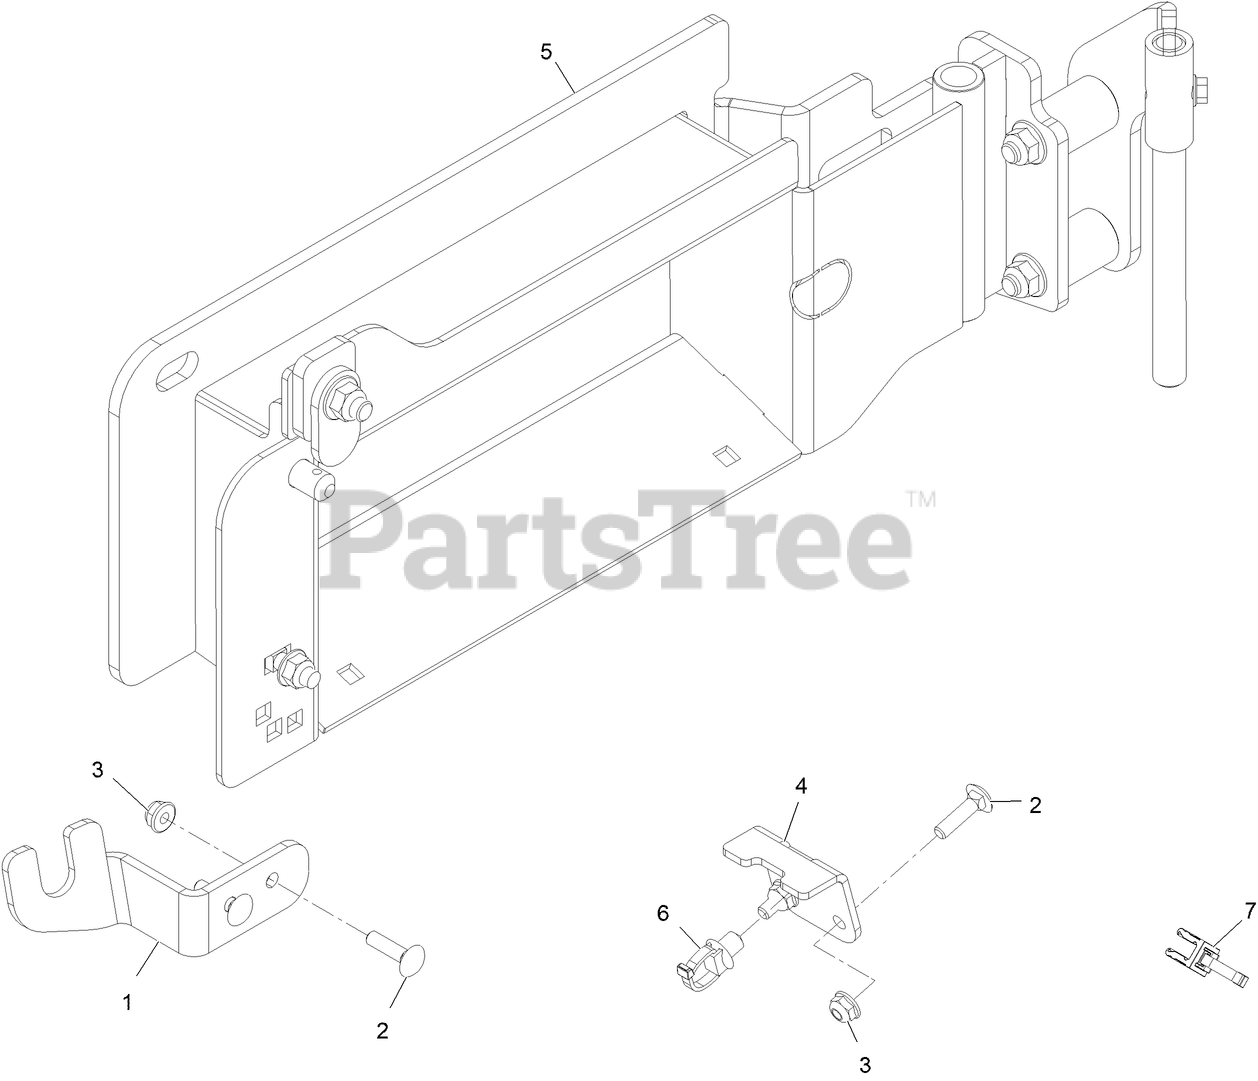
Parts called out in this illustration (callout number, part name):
1	BRKT-OCD CABLE
2	SCREW-CARR
4	BRKT-CABLE
5	KIT-ADAPTOR, ACCY. (SERIES 3)
6	CLIP-TIE
7	Clip-Edge
